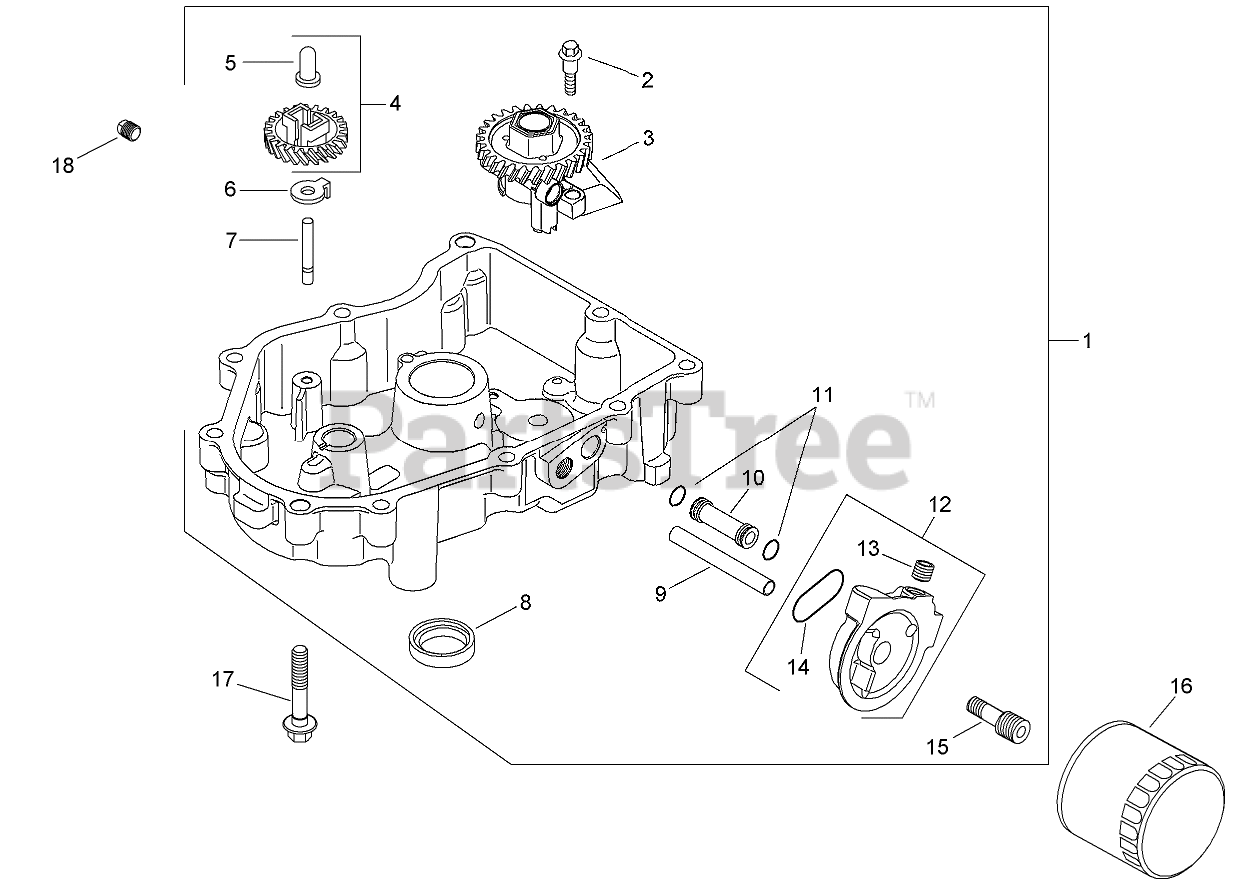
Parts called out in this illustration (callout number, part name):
1	OIL PAN ASM (INCLUDES 2-15)
2	SCREW-SHOULDER, THD FRM (M6x1.0x26.5)
3	OIL PUMP ASM
4	GOVERNOR GEAR W/PIN KIT
5	PIN-REGULATING, GOVERNOR
6	TAB-LOCKING
7	SHAFT-GEAR, GOVERNOR
8	SEAL-OIL
9	TUBE-FEED, OIL (FILTER TO PAN)
10	TUBE-FEED, OIL (PAN TO FILTER)
11	O-RING
12	ADAPTER OIL FILTER KIT
13	PLUG-PIPE, COUNTERSUNK (1/8)
14	O-RING (OIL FILTER ADAPTER)
15	NIPPLE-FILTER, OIL
16	FILTER-OIL
17	SCREW-FLANGE (M8X1.25X45)
18	PLUG-PIPE, SQ HD (3/8)
